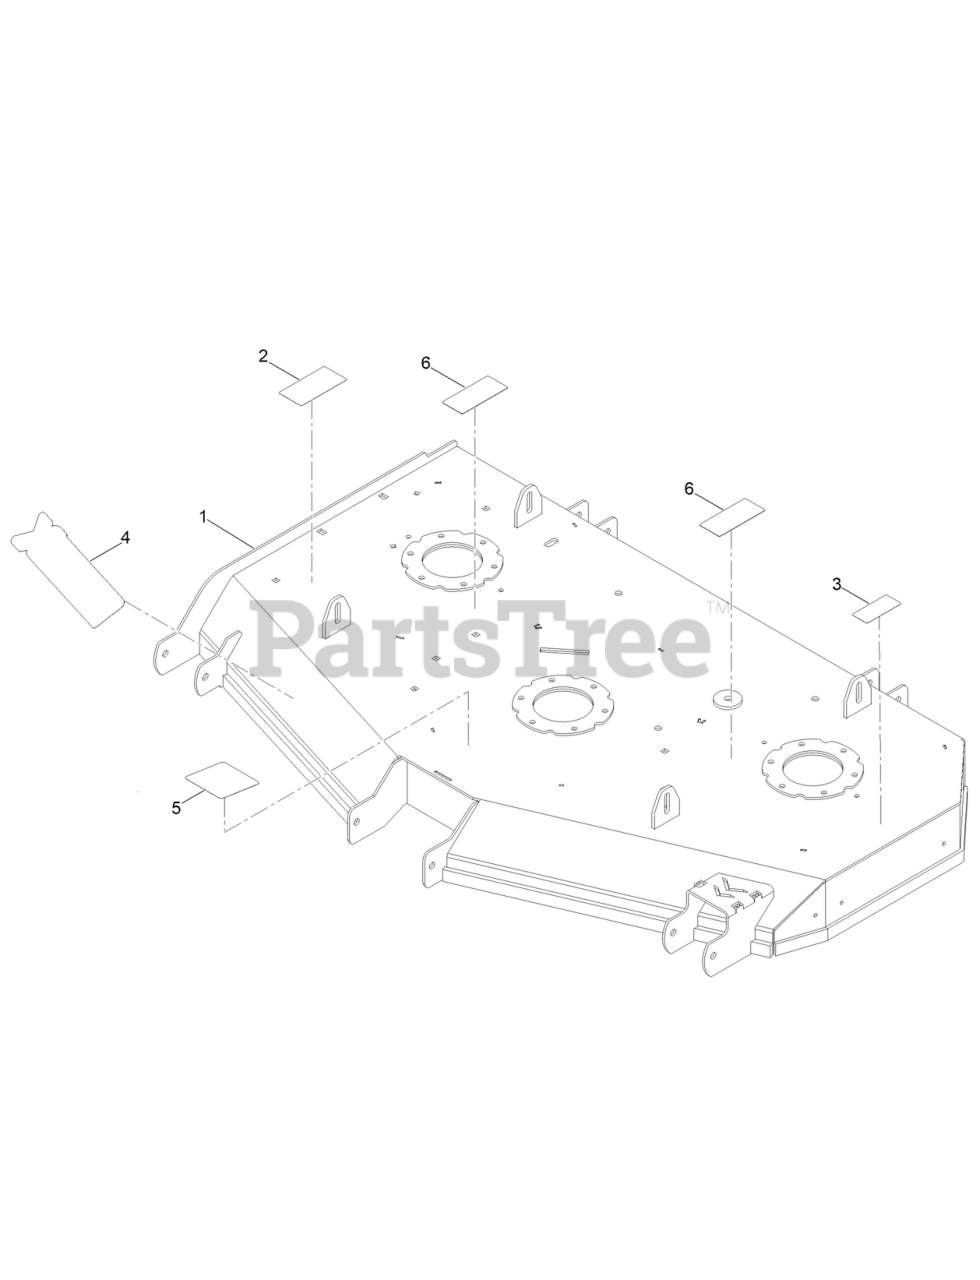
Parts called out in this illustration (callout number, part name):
1	DECK ASM-54 PAINTED BLACK
2	DECAL-DANGER, DECK
3	DECAL-SAFETY BLADE TORQUE
4	DECAL- XTF 54
5	DECAL-DECK BELT ROUTING
6	DECAL-ROTATING FAN HAZARD
